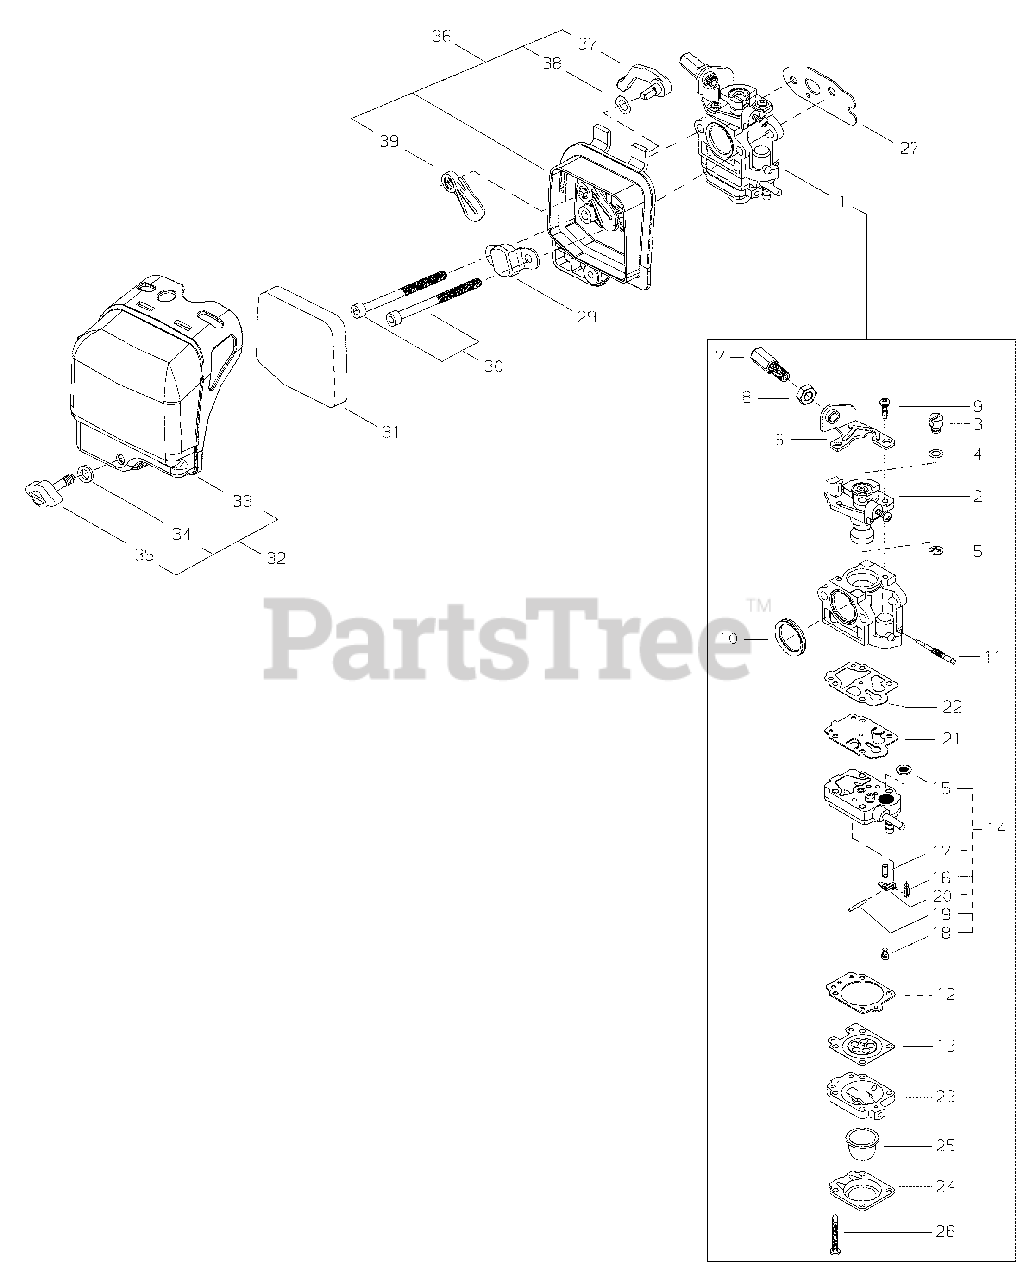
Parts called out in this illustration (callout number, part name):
1	CARBURETOR
2	VALVE ASSY, THROTTLE
3	SWIVEL
4	WASHER
5	E-RING
6	BRACKET, THROTTLE CABLE
7	ADJUSTER, THROTTLE CABLE
8	NUT, ADJUSTER LOCK M7
9	SCREW
10	RING, PACKING
11	NEEDLE, HIGH SPEED
12	GASKET, METERING DIAPHRAGM
13	DIAPHRAGM, METERING
14	BODY ASSY, PUMP
15	SCREEN, FUEL INLET
16	VALVE, INLET NEEDLE
17	SPRING, METERING LEVER
18	SCREW
19	PIN, METERING LEVER
20	LEVER, METERING
21	DIAPHRAGM, PUMP
22	GASKET, PUMP
23	BODY ASSY, PURGE
24	RETAINER, PURGE BULB
25	BULB, PURGE
26	SCREW
27	GASKET, CARBURETOR
29	BRACKET
30	BOLT M5×60
31	FILTER, AIR
32	COVER ASSY, AIR FILTER
33	COVER, AIR FILTER
34	WASHER 5
35	THUMBSCREW
36	BASE ASSY, AIR FILTER
37	LEVER, CHOKE
38	WASHER, WAVE
39	PLATE, CHOKE
